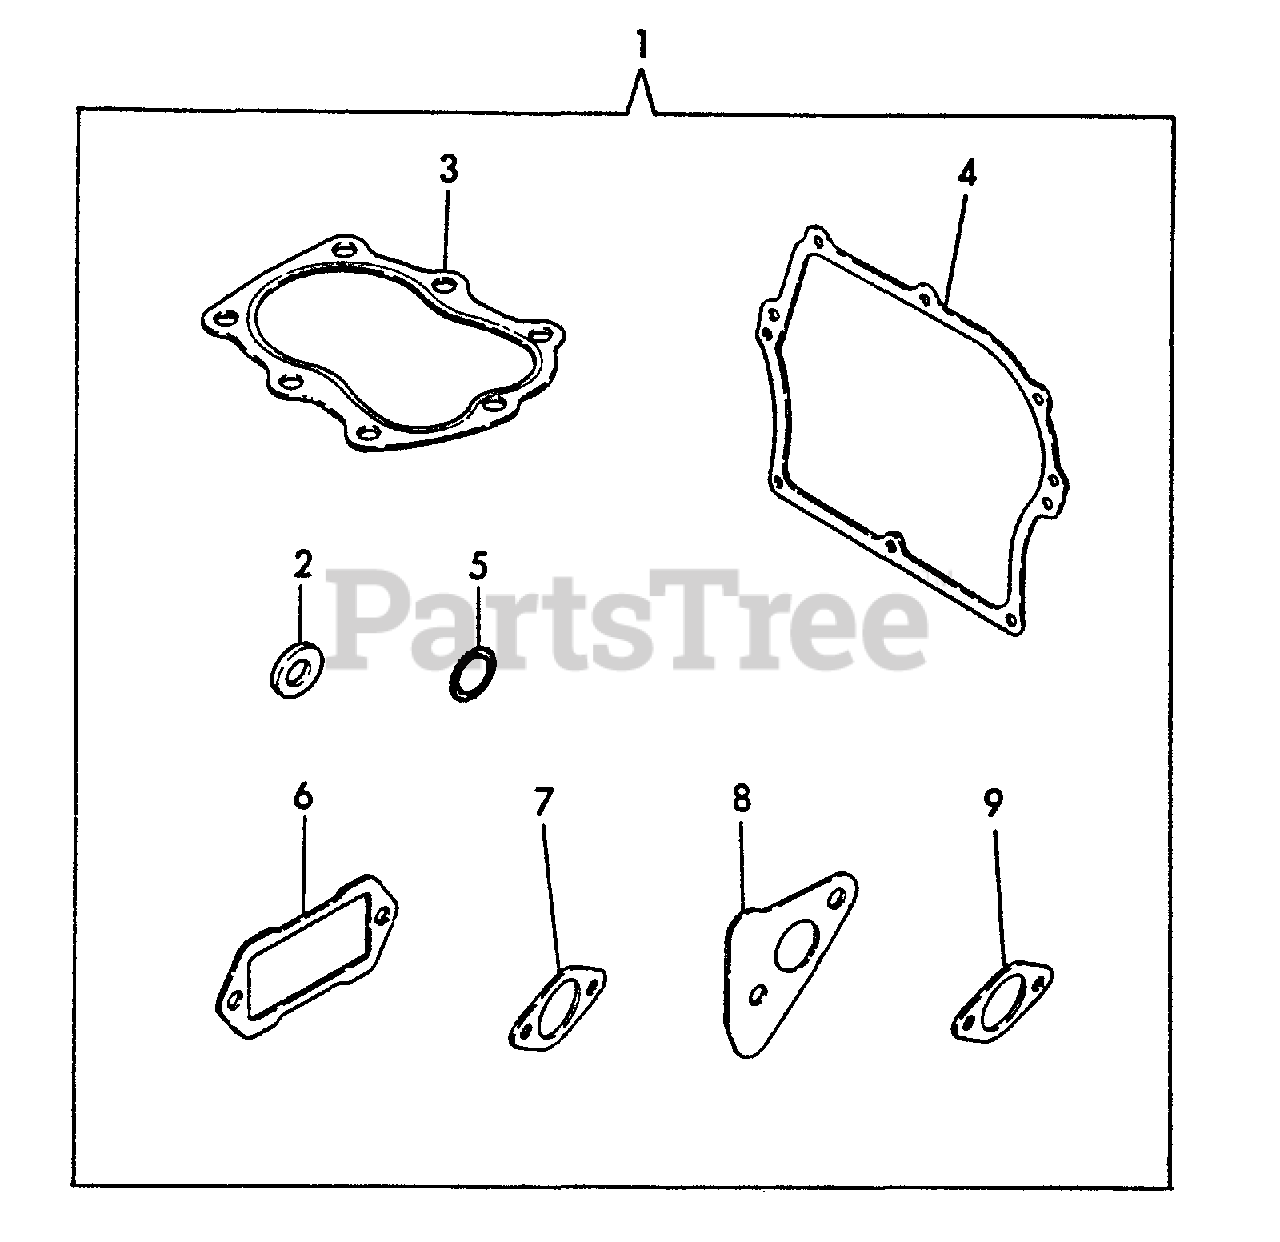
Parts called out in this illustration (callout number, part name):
1	GASKET KIT
2	GASKET
3	GASKET, CYLINDER
4	GASKET, SIDE COVER
5	O-RING 1A P-18.0
6	GASKET
7	GASKET, INTAKE
8	GASKET, EXHAUST
9	GASKET, EXHAUST
